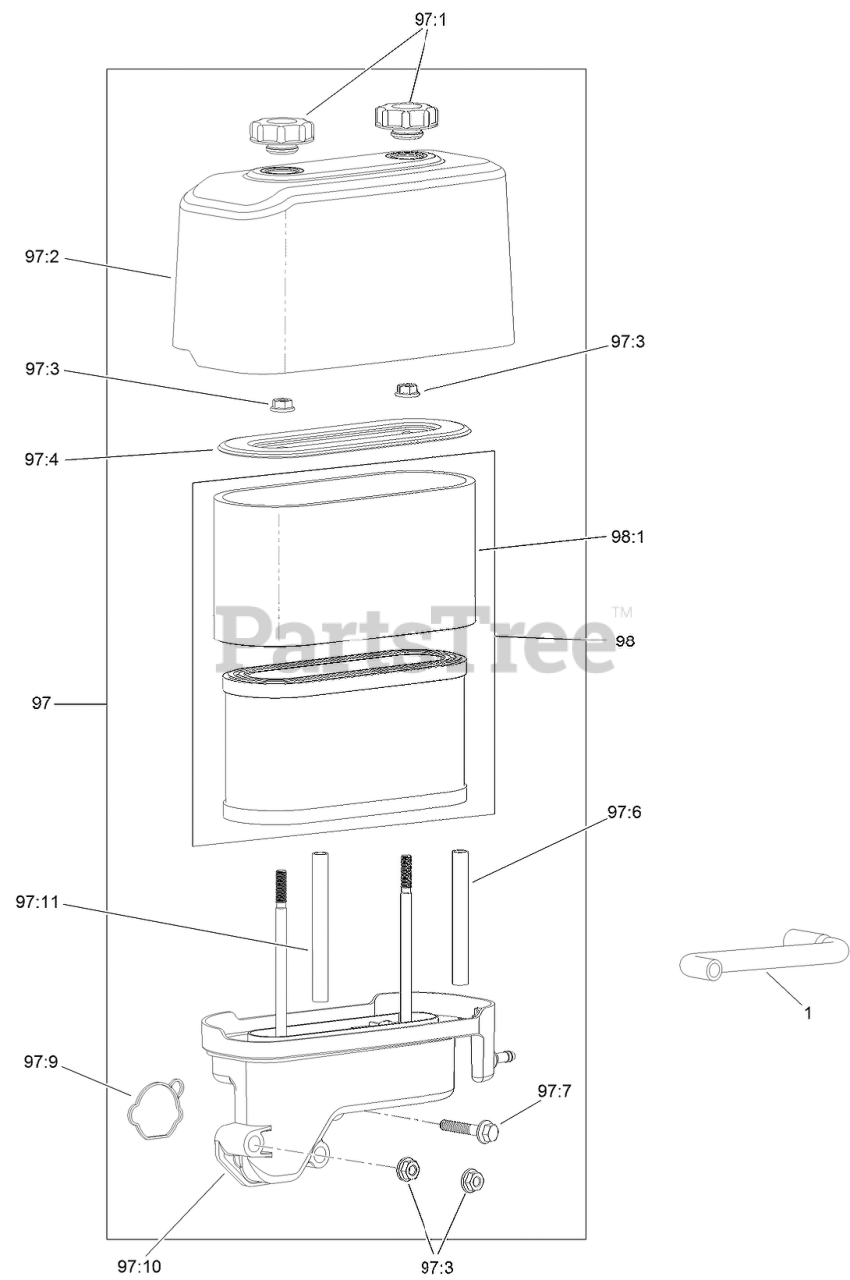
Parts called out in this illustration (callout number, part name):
1	TUBE-BREATHER
97	AIR CLEANER KIT
97:1	NUT-SPEED
97:2	COVER-FILTER, AIR
97:3	NUT-FLANGE
97:4	RETAINER-AIR FILTER
97:6	SPACER-FILTER, AIR
97:7	SCREW-HHF
97:9	GASKET-CARBURETOR
97:10	BASE-FILTER, AIR
97:11	SPACER-FILTER, AIR
98	AIR FILTER KIT
98:1	PREFILTER
